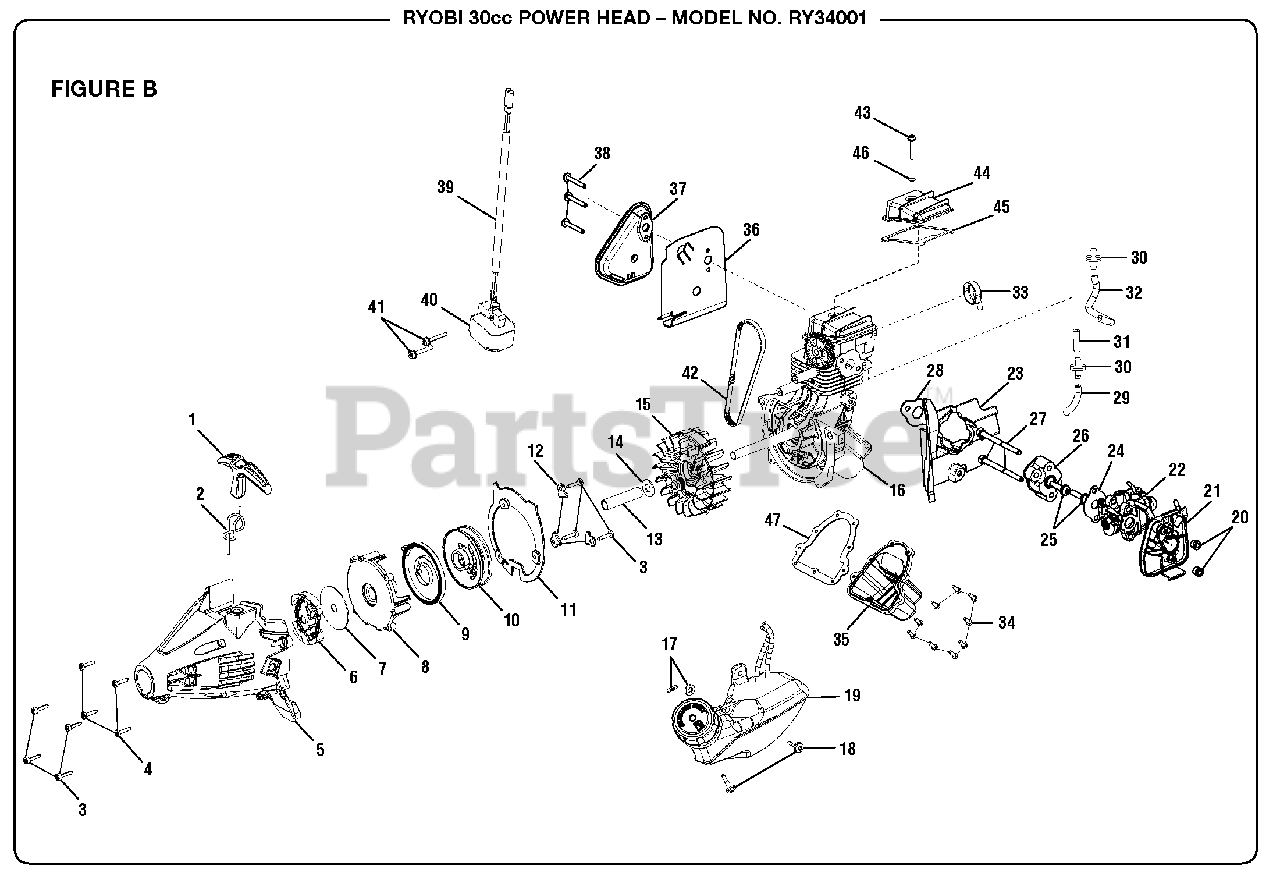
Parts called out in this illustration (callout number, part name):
1	Starter Grip
2	Starter Rope (42 in)
3	Screw (M4 x 18 mm)
4	Screw (M4 x 16 mm)
5	Starter Housing Assembly
6	Clutch Assembly
8	Starter Baffle
9	Spring & Container
10	Starter Pulley
12	Pulley Retainer
13	Spacer Tube
14	Washer
15	Flywheel Assembly
16	Short Block Assembly
18	Screw (M4)
19	Fuel Tank & Cap Assembly
20	Hex Nut (M5 x 0.8)
21	Air Filter Base
22	Carburetor Assembly
23	Air Baffle
24	Carburetor Gasket
25	Screw (M5 x 23 mm)
27	Bolt (M5 x 63 mm)
28	Heat Dam Gasket
29	Breather Hose
30	Check Valve
31	Breather Hose
32	Breather Hose
33	Breather Fitting
34	Screw (M4 x 12 mm)
36	Muffler Gasket
37	Muffler Assembly
38	Muffler Bolt (M5 x 42 mm)
39	Electrical Lead Wire Assembly
40	Ignition Module
41	Screw (M4 x 19 mm)
42	Timing Belt
43	Screw (M4 x 27 mm Total, w/14 mm Threaded)
44	Cam Cover
